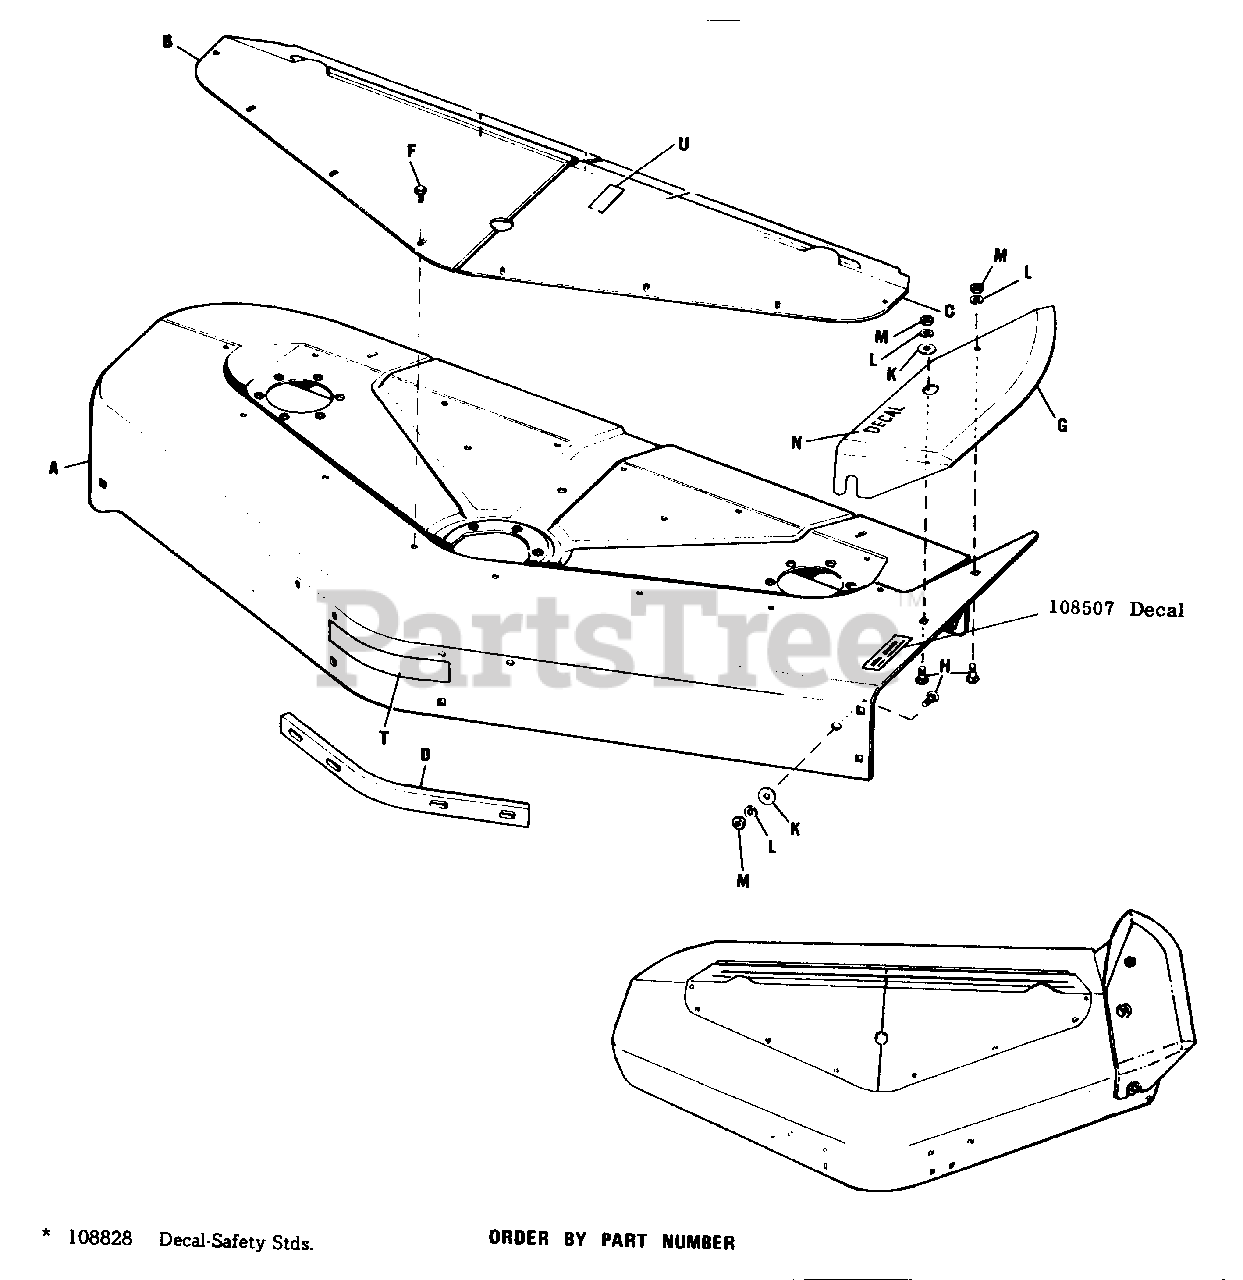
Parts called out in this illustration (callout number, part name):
A	Mower Housing
B	R.H. Cover
C	L.H. Cover
D	Reinforcing Bar
F	Self Tapping Screw, 1/4"-20 x 3/8" lg.
G	Deflector
H	Carriage Bolt,3t8"-16 x 3/4" lg.
K	Special Washer
L	Lock Washer, 3/8"
M	Hex Nut, 3/8"-16
P	Guide Belt Assembly
T	Film Simplicity
